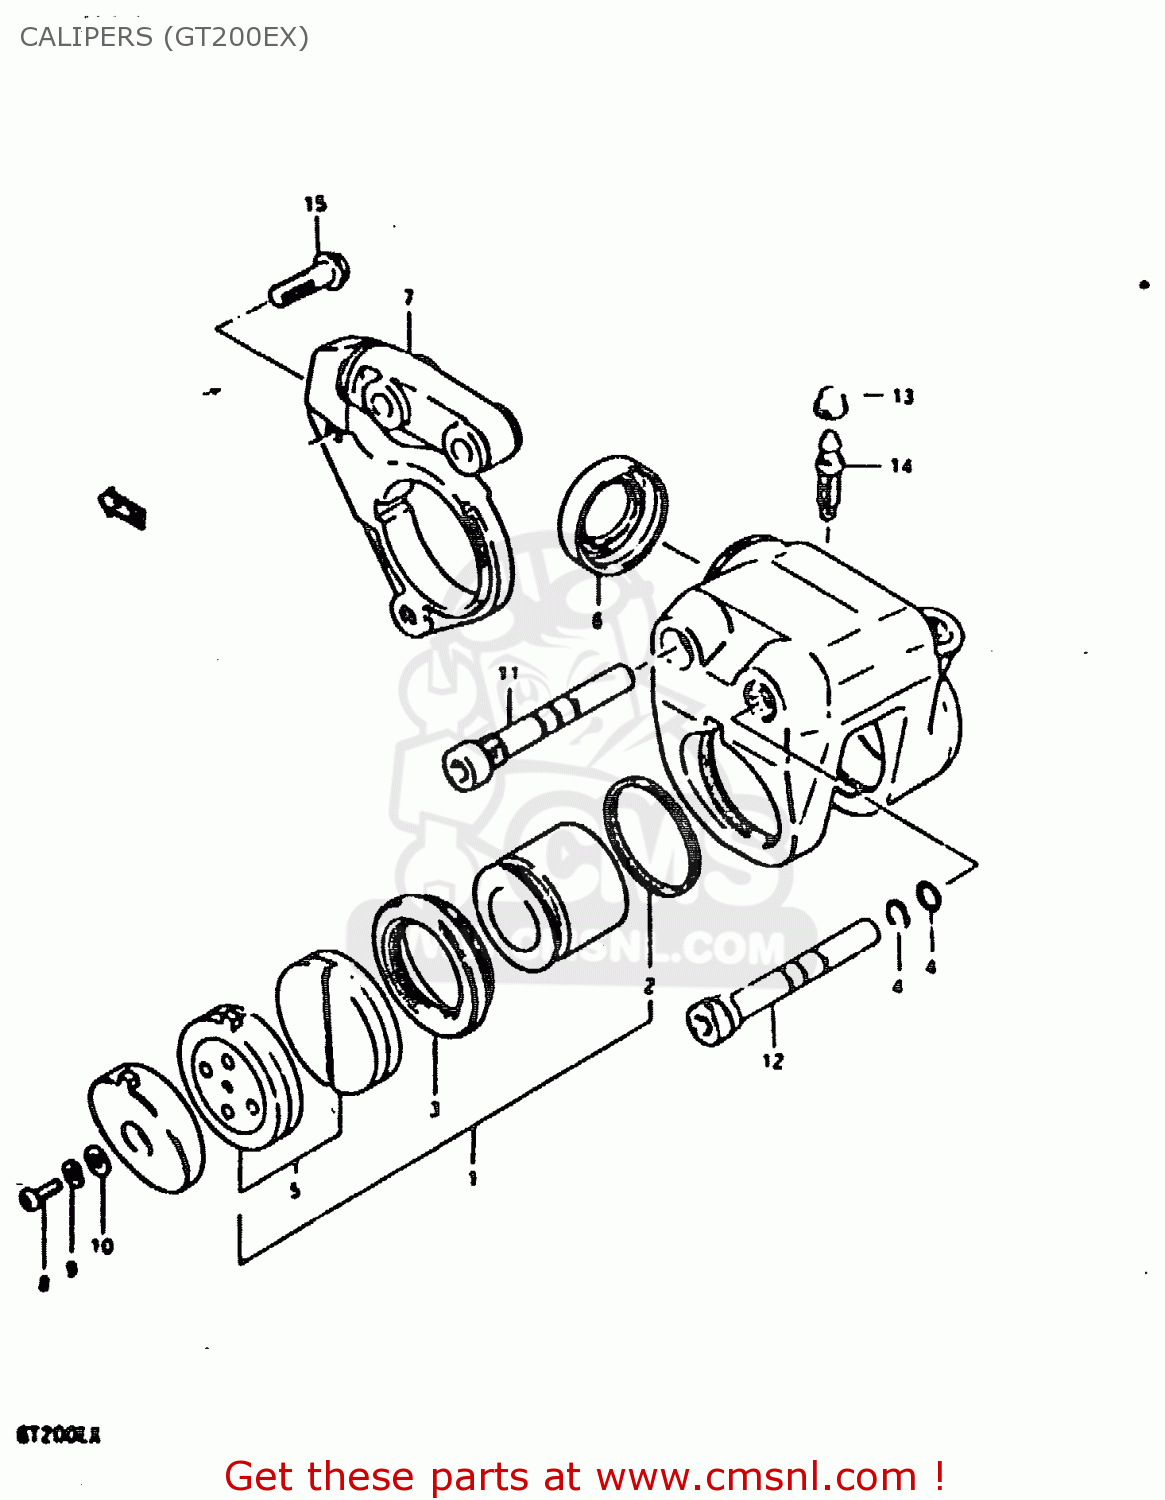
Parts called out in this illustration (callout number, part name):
1	PISTON & PAD SET
2	SEAL,PISTON
3	BOOT,PISTON
4	O RING,AXLE CALIPER
5	PAD SET
6	BOOT,HOLDER
7	HOLDER,CALIPER
8	SCREW
9	LOCK WASHER
10	WASHER
11	AXLE,CALIPER
12	AXLE NO.2
13	CAP,BLEEDER PL
14	BLEEDER
15	BOLT(10X37)
